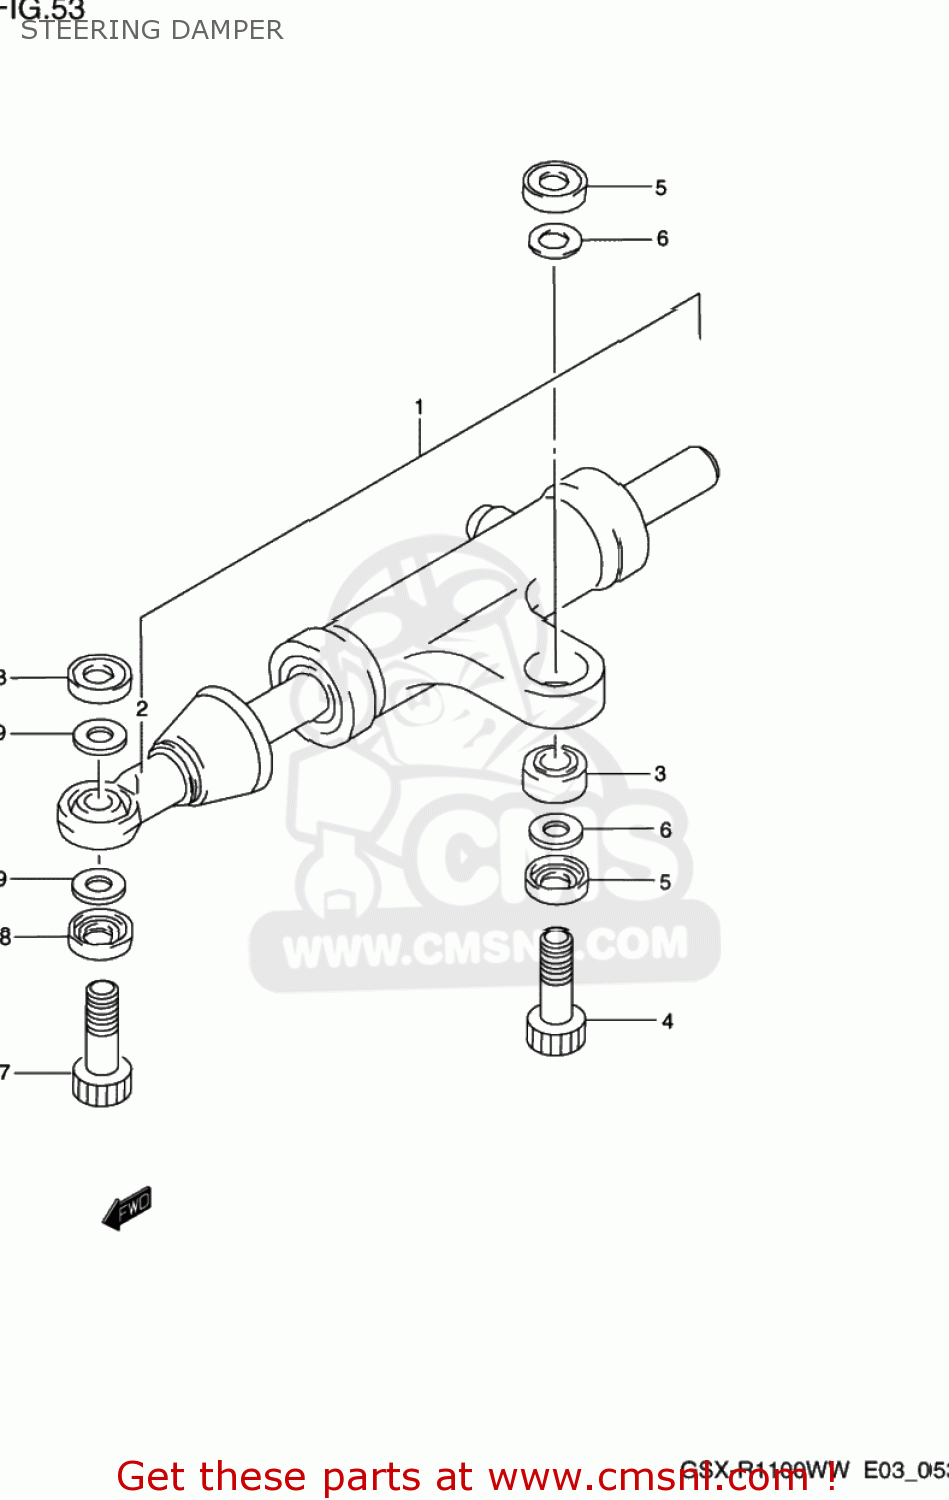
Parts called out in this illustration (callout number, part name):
1	DAMPER ASSY,STEERING
2	PILLOW BALL,ROD END
3	BEARING(8X17.5X11)
4	BOLT
5	6-1
6	SHIM
7	BOLT
8	9-1
9	SHIM
